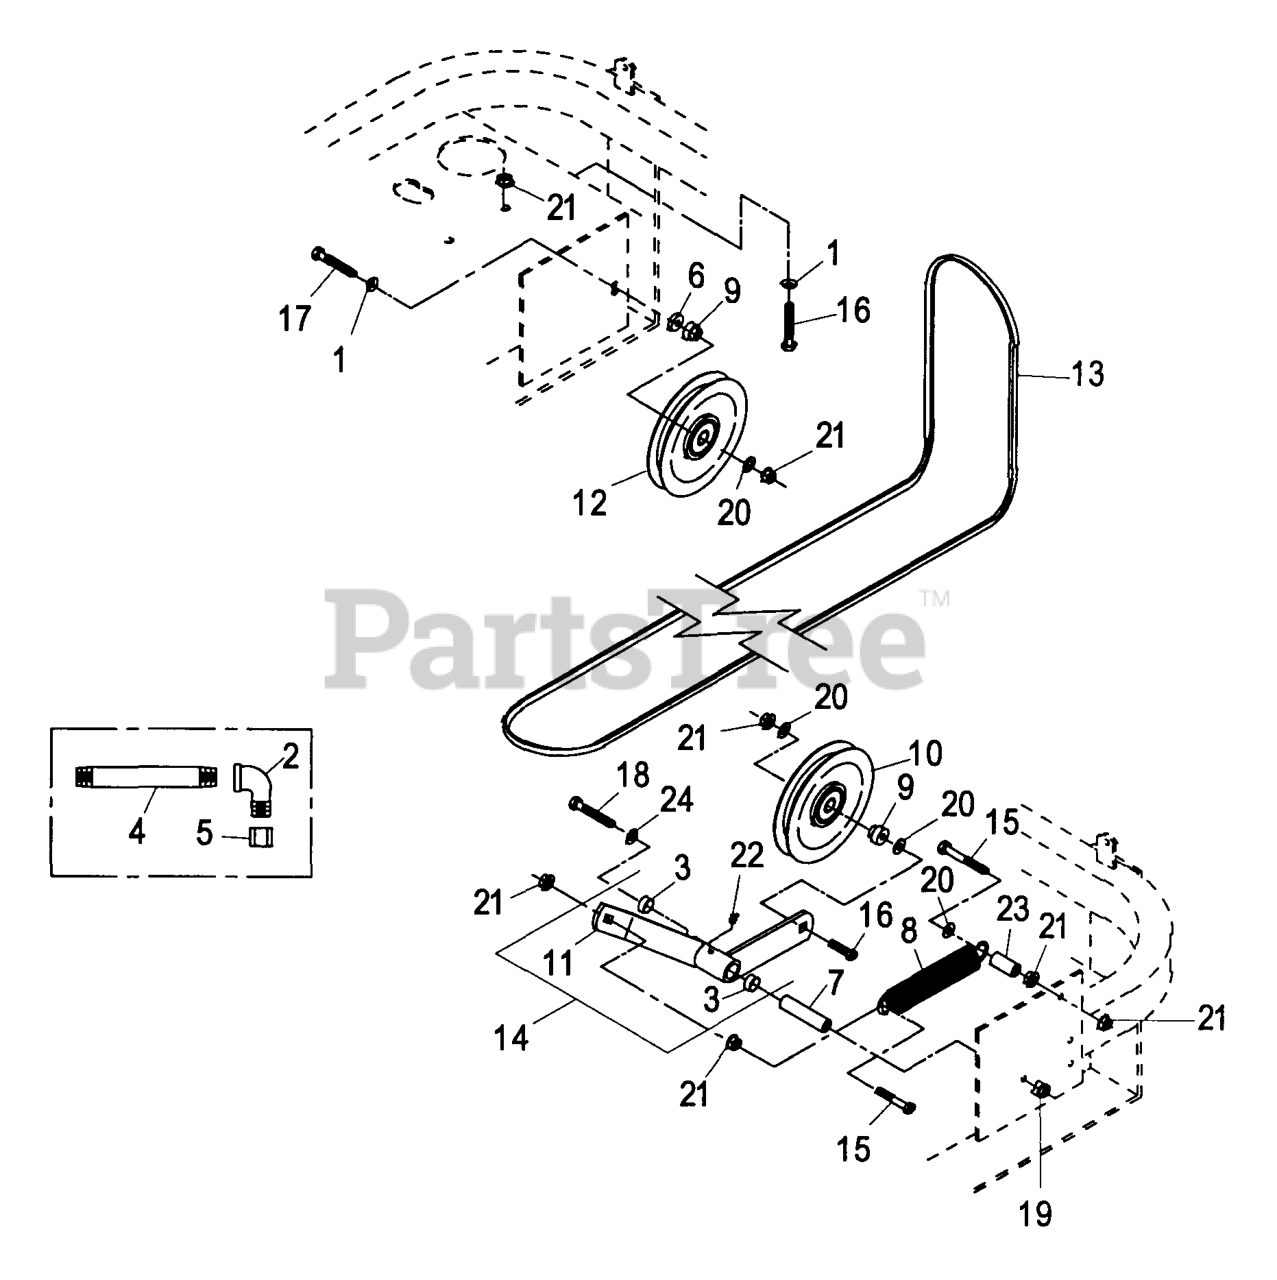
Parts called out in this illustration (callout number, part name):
2	ELBOW-90 DEG
3	SLEEVE-BEARING
4	NIPPLE
5	CAP-HEX
7	BUSHING-PIVOT, IDLER
8	SPRING-EXTENSION
9	BUSHING-IDLER
10	PULLEY-IDLER
12	PULLEY-IDLER
13	BELT,MULE DRIVE
14	ARM ASM
18	SCREW-HH
